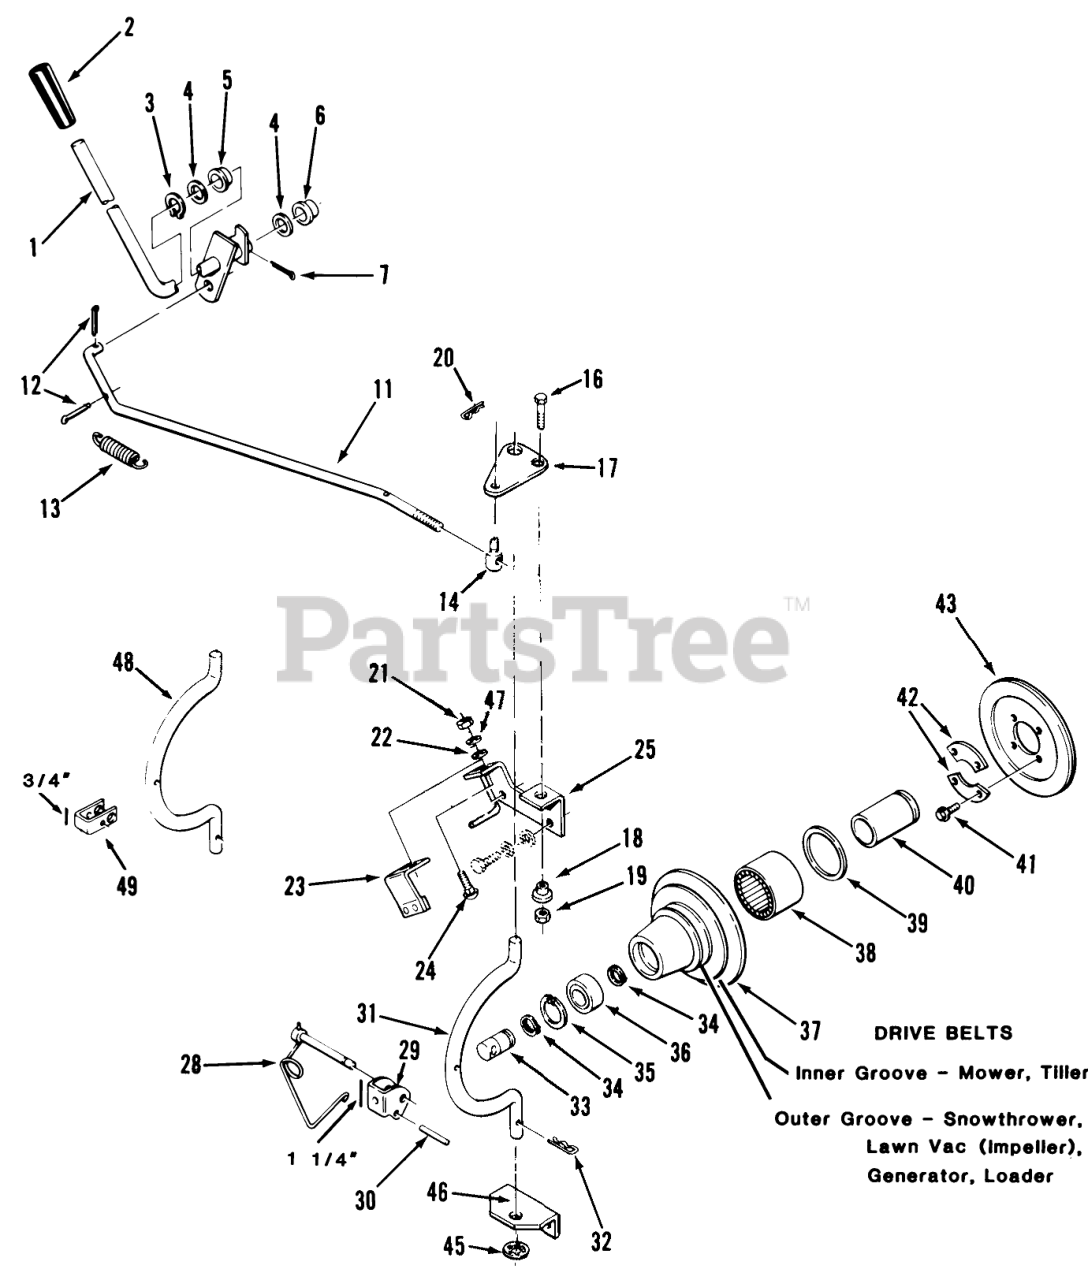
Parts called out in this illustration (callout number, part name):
1	ASSY PTO CLUTCH LEVE
2	GRIP
3	Grip Ring
4	SHIM-WASHER
5	BUSHING-NYLINER
6	NYLINER BUSHING
7	Pop Rivet
11	ROD-PTO CLUTCH
12	Pop Rivet
13	SPRING
14	TRUNNION
16	BOLT
17	PLATE
18	SPACER-LIFT LINK
19	Nut
20	Hairpin Cotter
21	Nut
23	ASM-Bracket
24	Bolt-Carriage
25	ENG BRACKET WAB
25	ASSY BRACKET ENG. B
25	Bracket
28	LOCKING PIN ASM
29	CLEVIS B
31	ROD-HOUSING
31	ROD HOUSING
32	Hairpin
33	SHAFT-PTO
34	RING-SNAP, EXTERNAL
35	Ring-Snap
36	BEARING-BALL
37	Housing-Clutch
38	BRG-NEEDLE OPEN END
39	SEAL-OIL
40	RACE-BEARING
40	BEARING RACE
41	H H C S
41	RACE-BEARING
42	RETAINER
43	Clutch Plate & Facing
45	RING-REINFORCED CIRC
46	Axle
47	Washer
48	ROD-HOUSING
48	PTO Housing Rod 418-s-Used With 3/4" Clevis
49	CLEVIS
49	PTO Housing Rod 418-s-Used With 3/4" Clevis
